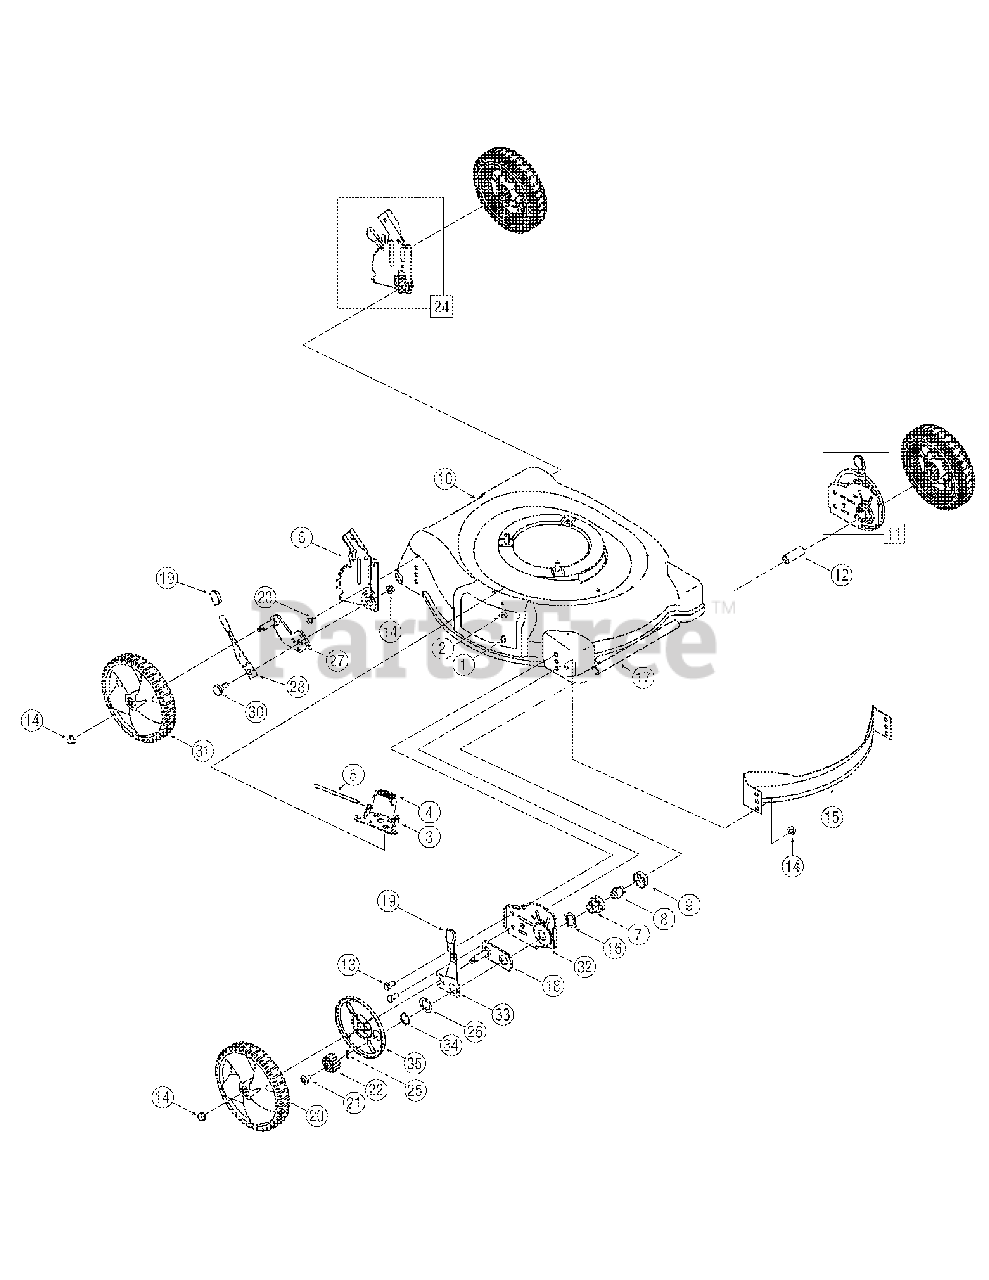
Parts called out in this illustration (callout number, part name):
1	TT Screw 1/4-20 x 0.5
2	Bell Washer.265 x 0.75
3	Deflector Chute Adapter
4	Torsion Spring
5	Hinge Pin
6	Handle Bracket - RH
6	Handle Bracket - LH
7	Bearing Support
8	Bearing Sleeve
9	Bearing Retainer
11	Height Adjustment Assembly - LH
12	Slev. Spacer 1.4" Lg.
13	Hex Screw, 3/8-16 x.75
14	Flange Lock Nut, 3/8-16
15	Front Baffle
16	Wave Washer
17	Sleeve Spacer 8.985" Lg.
18	Pivot Plate Assembly
19	Adjustment Knob
20	Front Wheel 8 x 1.8
21	Screw, 1/4-20 x .390
22	Gear 14T RH FWD
22	Gear 14T LH FWD
23	TT Scr. w/Washer 1/4-20 x.625
24	Handle Bracket Assembly - RH
24	Handle Bracket Assembly - LH
25	Dowel Pin
26	Washer
27	Pivot Arm Assembly - RH
27	Pivot Arm Assembly - LH
28	Rear Spring Lever
29	Hex Lock Nut, 3/8-24
30	Shoulder Scr.500 Dia. x.434
31	Rear Wheel, 8 x 1.8
32	Height Adjuster Plate - RH
32	Height Adjuster Plate - LH
33	Front Lever - RH
33	Front Lever - LH
34	Snap Ring
35	Wheel Dust Cap
